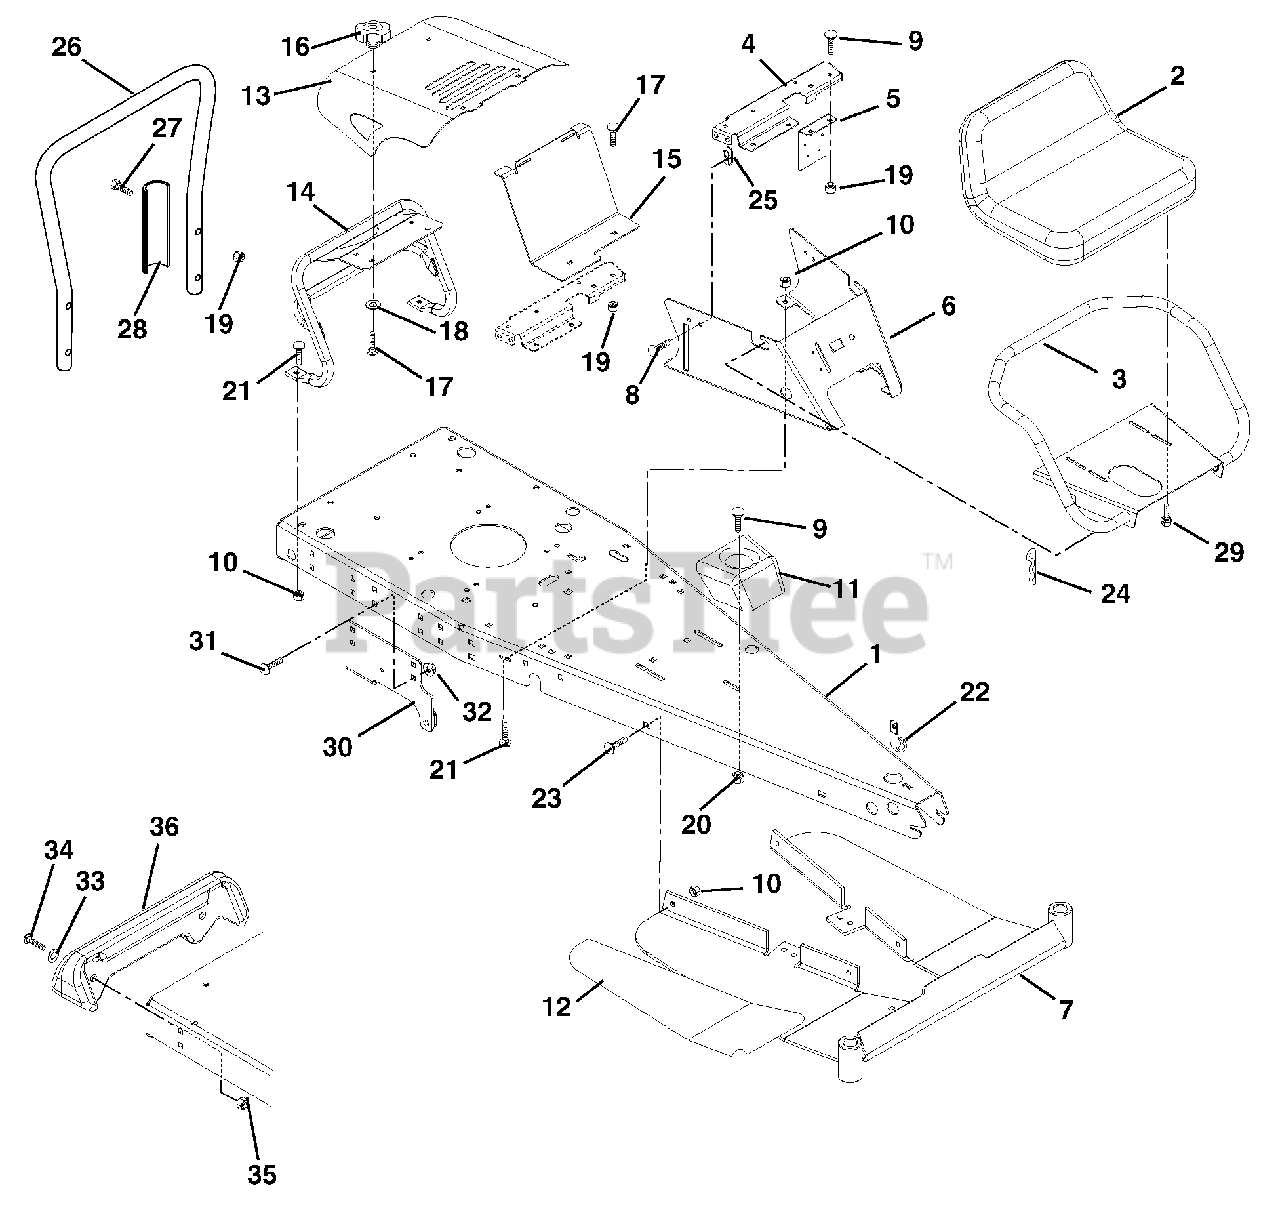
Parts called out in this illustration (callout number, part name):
2	Seat-Low Back TS2300
3	Weldment, Seat Plate and Armrest
4	Reforcement, Seat Support
5	Panel, Solenoid Mounting
6	Seat Support
7	Weldment-Footrest
8	Bolt-Serrated Hex Flange Washer Head .25-20 x .75
9	Bolt, Round Head Square Neck .31-18 x .75 Grade 5
10	Nut, Locking Top Flange .38-16
11	Cupholder
12	Grip, Rear Engine Rider Footrest Left Hand
12	Grip, Rear Engine Rider Footrest Right Hand
13	Engine-Hood (064)
14	Weldment Tube (064)
15	Bracket, Hood Support (064)
16	Knob, Clamping .31-18 Nyloc (064)
17	Bolt-Round Head Square Neck .31-18 x 1.00 (064)
18	Nut-Push .312 (064)
19	Nut-Locking-Top-Flange .31-18
20	Nut-Spin Lock-Flange .312-18
21	Bolt-Round Head Square Neck .38-16 x .75 Grade 5
22	J-Clamp
23	Bolt-Round Head Square Neck .38-16 x 1.00 Grade 5
24	Pin-Hair-External .12 x .31 x 2.37
25	Nut-Retainer .25-20 x .56
26	Stand Up Tube (060, 062)
27	Bolt, Hex .31-18 x 1.50 Grade 5 (060, 062)
28	Brace, Service Bar (060, 062)
29	Bolt-Serrated Hex Flange Washer Head .31-18 x 1
30	Bracket, Transmission - Right Hand
30	Bracket, Transmission - Left Hand
31	Bolt, Round Head Square Neck .38-16 x .75 Grade 5
32	Nut, Locking Top Flange .38-16
33	Washer-Flat-Steel .438 x 1.00 x .083
34	Bolt-Hex .38-16 x 1.75 Grade 5
35	Nut-Locking-Top-Flange .38-16
36	Weight
